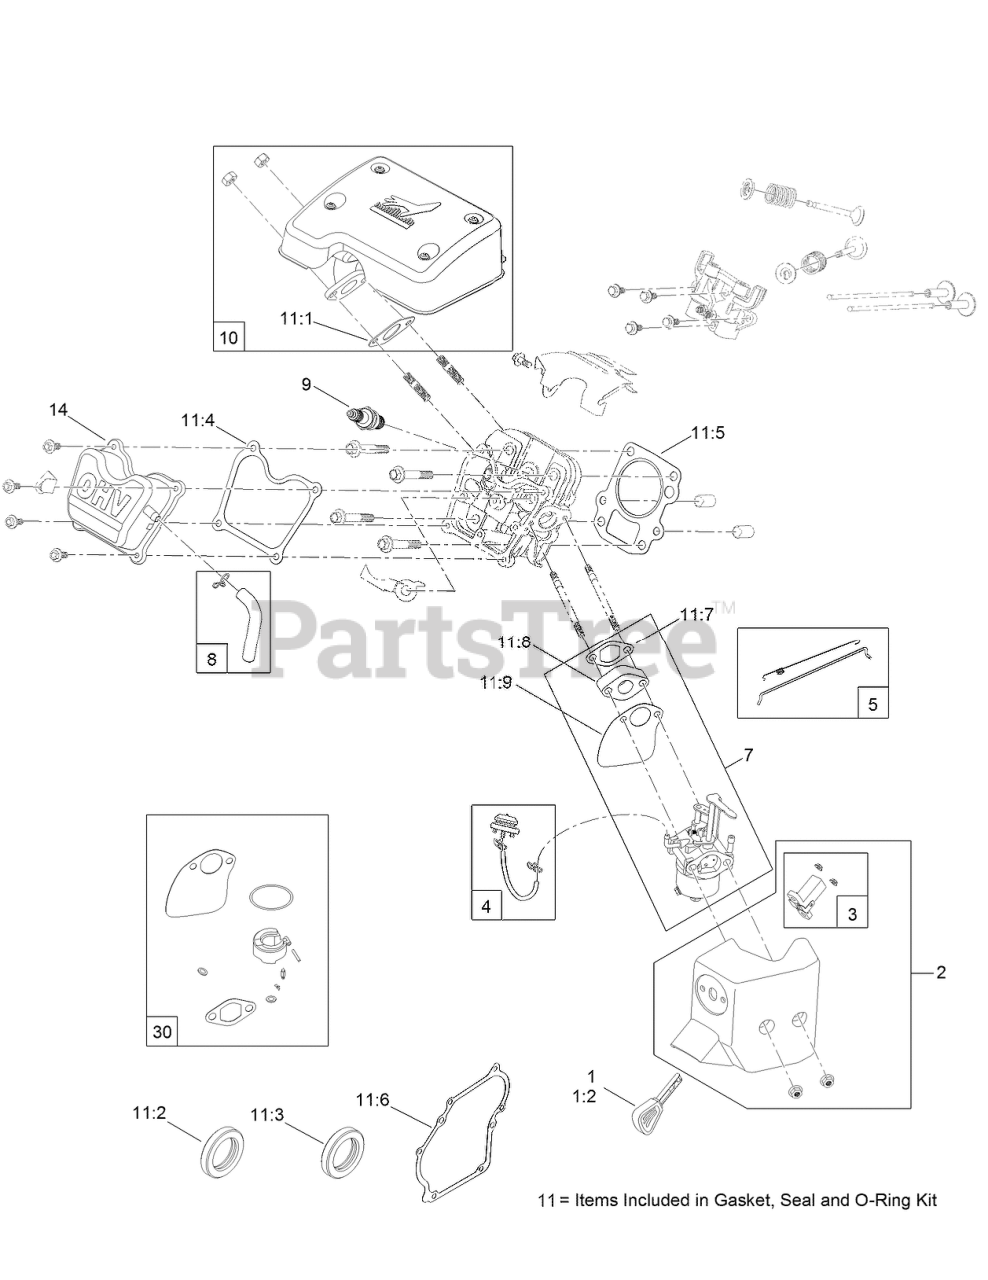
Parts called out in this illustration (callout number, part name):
1	KEY AND LANYARD KIT
2	HEATER BOX KIT
3	SWITCH KIT
4	PRIMER BULB KIT
5	GOVERNOR KIT
7	COMPLETE CARB SERVICE KIT
8	BREATHER TUBE KIT
9	SPARK PLUG
10	MUFFLER KIT
11	GASKET, SEAL AND O-RING KIT
11:1	Gasket-Exhaust
11:2	Seal-Oil
11:3	Seal-Oil
11:4	GASKET-COVER, VALVE
11:5	GASKET-HEAD, CYLINDER
11:6	GASKET-COVER, CRANKCASE
11:7	GASKET-INSULATOR
11:8	INSULATOR-CARBURETOR
11:9	GASKET-CARBURETOR
14	VALVE COVER ASM
30	CARBURETOR REPAIR KIT
